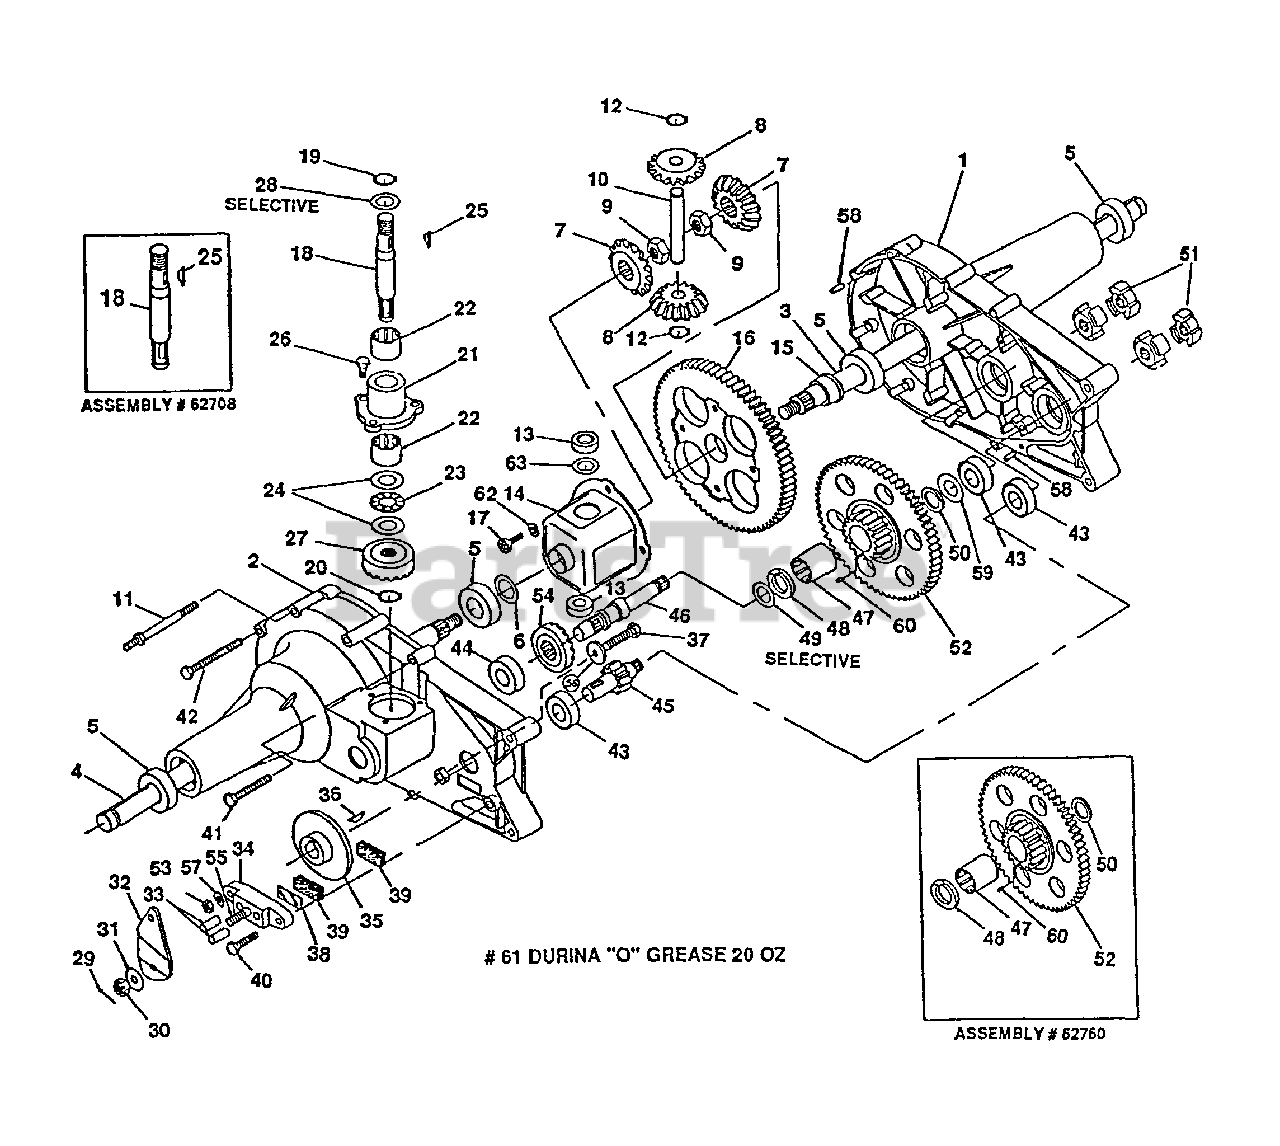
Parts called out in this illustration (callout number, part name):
1	HOUSING HALF LH
2	HOUSING HALF RH
3	AXLE LH 3/4"
4	AXLE RH 3/4"
5	BEARING, BALL
6	WASHER, FLAT 3/4ID X 1-1/8 00 X .030 THK
7	GEAR, MITER
8	GEAR, MITER
9	NUT, HEX JAM W/PATCH 1/2-20
10	SHAFT. CROSS
11	SCREW/STUD
12	SNAP RING
13	BEARING, THRUST
14	HOUSING ASSY, DIFFERENTIAL
15	BEARING, FLANGE
16	GEAR, DIFFERENTIAL 72 TOOTH
17	BOLT, TORX HEAD 1/4-28 X 5/8" LG.
18	SHAFT, INPUT
19	SNAP, RING
20	RETAINING RING 7/16" DIA. EXT.
21	HOUSING, INPUT BEARING
22	BEARING, NEEDLE
23	BEARING, THRUST
24	WASHER, FLAT 5/8 ID X 1-1/8 OD X .030 THK
25	KEY. HI-PRO 3/32 X 5/8 DIA.
26	SCREW; HEX W/PATCH 1/4-20 X 3/4 LONG
27	GEAR, INPUT PINION 17 TOOTH
28	WASHER, FLAT .62 10 X 1.0 00 X .050 THK
28	WASHER, FLAT .62 10 X 1.125 OD X .060 THK
28	WASHER, FLAT .62 10 X 1.0 OD X .040 THK
29	PIN, COTTER
30	NUT, CASTLE 5/16-24
31	WASHER, FLAT .343 ID X .88 OD X .062 THK
32	ARM, BRAKE ACTUATOR
33	PIN. BRAKE ACTUATING
34	BRAKE, YOKE
35	DISC, BRAKE
36	KEY. HI-PRO 3/16 X 5/8" DIA.
37	SCREW HEX 1/4-20 X 1.50 LONG
38	PLATE. PUCK
39	PUCK, BRAKE
40	SCREW, HEX W/PATCH 1/4-20 X 1.00 LG
41	SCREW, HEX SELF-TAP 1/4-20 X 2.00 LG.
42	SCREW, HEX SELF-TAP 1/4-20 X 3.00 LG.
43	BEARING, BALL
44	BEARING. BALL
45	SHAFT, PINION W/11 TOOTH GEAR
46	SHAFT, DRIVE
47	BEARING, NEEDLE
48	BRONZE THRUST BRG 5/8 ID X 1-1/4 00 X 7/64 THK
49	WASHER, FLAT .62 ID X 1.0 00 X .040 THK
49	WASHER, FLAT .62 ID X 1.0 00 X .050 THK
50	SEAL, GREASE
51	COUPLING
52	GEAR, 60 AND 17 TOOTH
53	NUT, HEX 114-20
54	GEAR, DRIVE PINION 17 T.
55	BOLT, SQUARE HEAD
56	WASHER, 15/16 00 X .265 ID X .125 THK
57	WASHER, 1/4" SPRING LOCK
58	PIN, ROLL 3/16" DIA X 1/2" LG.
59	WASHER, FLAT .62 ID X 1.0 OD X .030 THK
60	PIN. DOWEL 3/32 X 1/4
61	SHELL DURINA-O GREASE (20 OZ.)
62	WASHER, HD SPRC LOCK 1/4" (YELLOW DI-CHROM)
63	WASHER, FLAT .50 ID X 1.0 OD X .020 THK
63	WASHER, FLAT .50 ID X 1.0 OD X .030 THK
